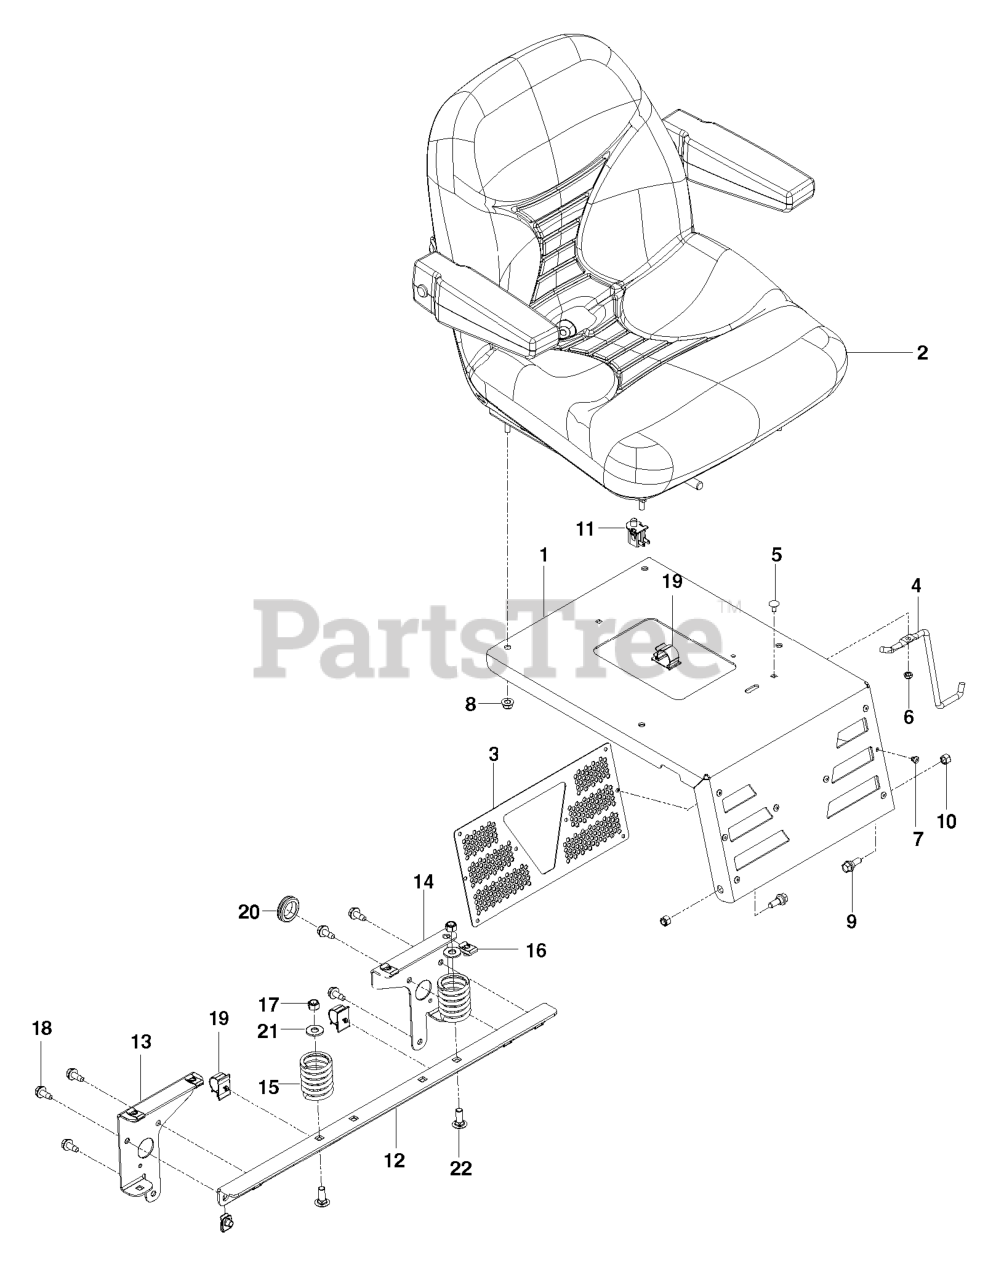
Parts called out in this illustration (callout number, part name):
1	SEAT MOUNT W/DECAL
2	SEAT
3	PANEL, HEX
4	STOP, SEAT, FORWQARD
5	RHSSNB 1/4-20 X 1/2
6	JAM NUT 1/4C (2 2 PW01)
7	RIVET, 3/16" - .06-.25 GRIP
8	5/16-18 NYLOC FLANGE NUT
9	SB 5/16-18 HEX HD GD5, BLK ZN
10	NUT 5/16 NYLOC
11	SEAT SWITCH
12	SUPPORT, SEAT
13	SUPPORT, LT
14	SUPPORT, RT
15	SPRING, SEAT
16	U-CLIP 5/16-18 NUT RETAINER
17	NUT 3/8-16 NYLOC
18	BOLT 5/16-18 X 3/4
19	PUSH-MOUNT WIRE CLIP
20	RUBBER GROMMET
21	WASHER 3/8 FLAT
22	RHSNB 3/8C X 1
